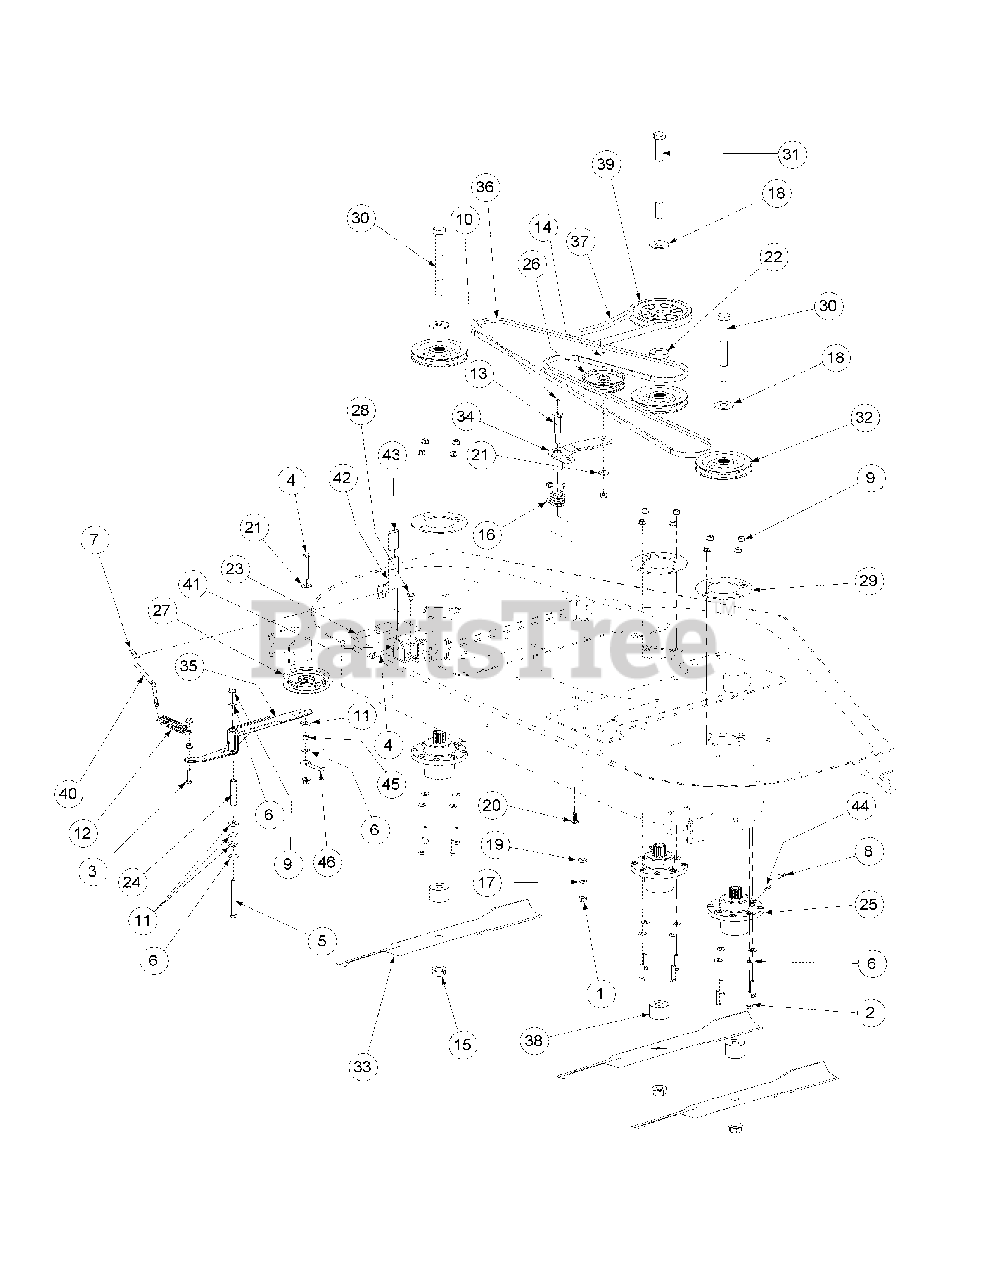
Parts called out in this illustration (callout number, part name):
1	Hex Nut, 7/16-14
2	Hex Cap Screw, 3/8-16 x 1-1/2
3	Hex Cap Screw, 3/8-16 x 1-1/4
4	Hex Cap Screw, 3/8-16 x 2-1/2
5	Hex Cap Screw, 3/8-16, 4.00
6	Flat Washer, 3/8
7	Cotter Pin, .072 x 1.12 Long
8	Taper Grease Fitting, 1/4-28, 45 degree
9	Flange Lock Hex Nut, 3/8-16
10	Grease Fitting, 1/4-28 x 3/16
11	Idler Washer
12	Extension Spring, 1.0 x OD x 5.00
13	Shoulder Screw, 7/16-14
14	Hex Carriage Screw, 3/8-16, 1.75
15	Flange Hex Nut, 3/4-16
16	Torsion Idler Spring
17	Lock Washer, 7/16
18	Spacer .812 ID x .268 LG
19	Flat Washer, .469 ID, .875 OD, .105
20	Carriage Bolt, 3/8-16 x 1
21	Flat Washer, .406 ID, 1.0 OD, .105
22	Spacer, .76 ID x 2.0 OD x .477
23	Spacer, .39 ID x .63 OD x 1.75
24	Spacer, .39 ID x .625 OD x 2.75
25	Aluminum Spindle Assembly
26	Flat Pulley
27	Idler Pulley, 4.06 OD
28	Screw, TT, 3/8-16 x .50,
29	Aluminum Spindle Support Plate
30	Hex Cap Screw, 3/4-16, 7.50
31	Hex Cap Screw, 3/4-16, 9.50
32	V-Pulley, 5.75 OD
33	Bahia Blade, 25.0, .756 ID
34	Idler Arm Assembly, Deck
34	Bearing Sleeve
35	Idler Arm Assembly, Drive
36	V-Belt, B Section x 124.0 LG
37	V-Belt, B Section x 155 LG
38	Spacer, .760 ID x 2.00 OD x .330
39	V-Pulley, 6.95 OD x .750 Bore, Cast
40	Spring Tension Rod
41	Tension Idler U-Bracket
42	Handle Tension Weldment
43	Tension Idler Handle Grip
44	Straight Adapter Fitiing
45	Hex Nut, 3/8-16
46	Belt Guide
